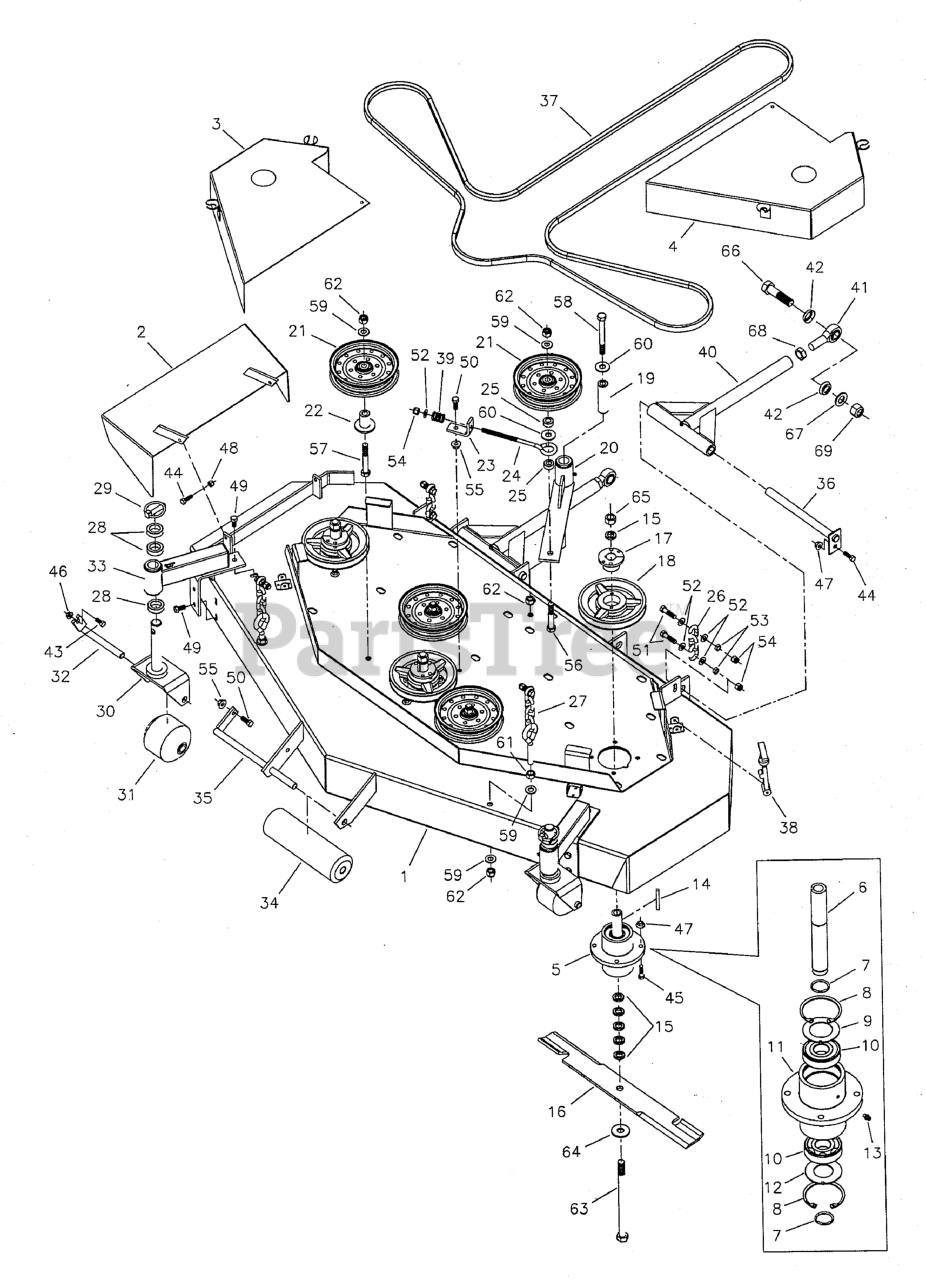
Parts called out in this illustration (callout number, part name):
1	DECK SHELL W/DECALS, 61, Z61
2	CHUTE, DISCHARGE WELDMENT
3	SPINDLE COVER-RH
4	SPINDLE COVER-LH
5	SPINDLE ASSEMBLY, Complete
6	SPINDLE SHAFT
7	SNAP RING, External
8	SNAP RING, Internal
9	SPINDLE WASHER, Top
10	BEARING
11	SPINDLE HOUSING
12	SPINDLE WASHER, Bottom
13	GREASE FITTING
14	KEY, 1/4 SQ. X 2-1/2
15	SPACER, .63 x 1.06 x .23
16	MOWER BLADE, 21"
17	BUSHING, Tapered Hub
18	PULLEY, Spindle
19	SPACER, .52 x 1.00 x 3.50
20	IDLER ARM ASSEMBLY
20	BUSHING, FLANGE
20	GREASE FITTING
20	IDLER ARM
22	IDLER PULLEY MOUNT
23	SPRING ANCHOR
24	EYEBOLT, 3/8" x 8"
25	SPACER, .52 x 1.00 x .44
26	CHAIN, 3 LINKS
27	HANGER, FRONT DECK - 4 LINK, 5.5" EB
28	SPACER, 1.02 x 1.56 x .50
29	PIN, Lynch
30	CASTER YOKE
31	ROLLER, Caster
32	CASTER ROLLER PIN
33	ARM, DECK CASTER ASSEMBLY
33	DECAL, Grease Daily
33	GREASE FITTING
33	BUSHING, FLANGE
33	CAP, Plastic
34	ROLLER
37	BELT, 5V, 175.90EL, LG ARAMID, WRPD, RC
38	RUBBER LATCH
39	SPRING, Compression
40	ASSM, DECK PUSHER BAR
41	BALL JOINT, 3/4-16 Male
42	ROD END SEAL
43	BOLT, 5/16-18 X 3/4 GD5
44	BOLT, 5/16-18 X 1 GD5 YZ
45	BOLT, 5/16-18 x 1-1/4
46	NUT, 5/16-18 HEX SERRATED FLANGE (SMALL)
47	NUT, 5/16-18 HEX SERRATED FLANGE (LARGE)
48	NUT, 5/16-18 Hex Nylon Lock
49	BOLT, 3/8-16 X 3/4" GD5 CZ
50	BOLT, 3/8-16 X 1" GD5 CZ
51	BOLT, 3/8-16 X 1-3/4" GD5 CZ
52	WASHER, 3/8 SAE
53	NUT, 3/8-16 HEX JAM
54	NUT, 3/8-16 HEX NYLON LOCK
55	NUT, 3/8-16 Hex Serrated Flange
56	BOLT, 1/2-13 X 3" GD5 CZ
57	BOLT, 1/2-13 X 3-1/2, HEX HD, GD5, CZ (SV)
58	BOLT, 1/2-13 x 4-1/2
59	WASHER, 1/2 SAE
60	WASHER, 1/2" USS
61	NUT, 1/2-13 Hex
62	NUT, 1/2-13 HEX NYLON LOCK
63	BOLT, 5/8-11 x 9-1/2
64	WASHER, 5/8" USS
65	NUT, 5/8-11 Hex
66	BOLT, 3/4-16 x 3
67	WASHER, 3/4 SAE
68	NUT, 3/4-16 Hex Jam
69	NUT, 3/4-16 Hex Nylon Lock
